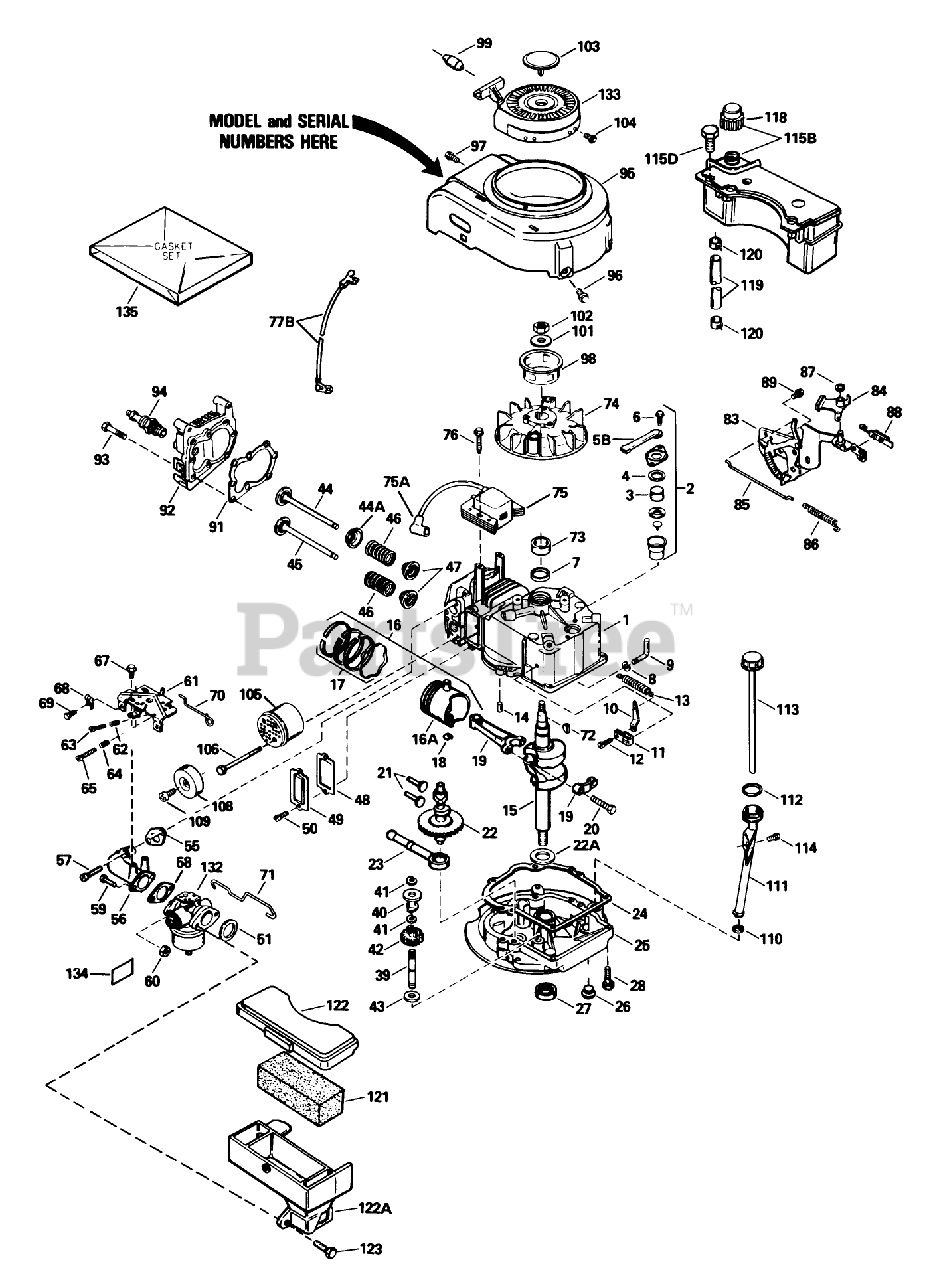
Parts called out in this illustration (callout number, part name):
1	Cylinder Assy. (Incl. #24)
2	Breather Assy. (Incl. Ref. #46 thru 51)
3	Element-Breather
4	Gasket-Breather
5B	Tube, Breaker
6	Screw (10-24 x 9/16)
7	Seal-Oil
8	Washer-Flat
9	Rod, Governor (Incl. No. 36)
10	Governor Lever
11	Clamp-Lever, Governor
12	Screw
13	Spring Governor
14	Pin-Dowel
15	Crankshaft
16	Piston-Pin Ring Assy. (Std.)(Incl. Ref. #16A, 17 18)
16	Piston-Pin Ring Assembly (.010 oversize)(Incl. Ref. #16A, 17 18)
16	Piston, Pin Ring Assy. (.020 Oversize)(Incl. Ref. #13A, 14, 15)
16A	Piston Pin Assy. (Std.)(Incl. Ref. #14)
16A	Piston Pin Assembly (.010 oversize)(Incl. Ref. #18)
16A	Piston Pin Assy. (.020 Oversize) (Incl. Ref. #14)
17	Ring Set-Piston (Std.)
17	Ring Set, Piston(.0100versize)
17	Ring Set (.020" OS)
18	Ring-Retaining, Piston Pin
19	Rod Assy., Connecting (Incl. Ref. #17)
20	Bolt-Rod, Connecting
21	Lifter-Valve
22	Camshaft(Mech.Comp. Release)
22A	Washer-Thrust
23	Oil Pump ASM
24	Gasket
25	Flange-Mounting (Incl. Ref. #26, 27 39)
26	Plug Oil Drain
27	Seal-Oil
28	Screw (1/4-20 x 1-1/4)
39	Shaft-Governor
40	Spool-Governor
41	Ring-Retaining
42	Governor Gear ASM
43	Washer
44	Valve, Intake (Std.) (Incl. Ref. #40)
44	Valve, Intake (1/32" oversize)(Incl. No. 40)
44A	Seal Assy., Intake
45	Valve, Exhaust (Std.)(Incl. No. 40)
45	Valve, Intake (1/32" oversize)(Incl. No. 40)
46	Spring-Valve
47	Cap-Valve, Spring
48	Gasket-Cover, Valve
49	Cover-Valve
50	Screw
51	Gasket-Cleaner, Air
55	Gasket-Intake Pipe
56	Pipe-Intake (Incl. Ref. #59)
57	Screw (1/4-20 x 1)
58	Gasket
60	Nut and Lock Washer (1/4-28)
61	Control Assy.-Remote Speed (Incl. Ref. #69 thru 72 76)
62	61709/GIL1515A/95-5
63	Screw
64	Spring-Compression
65	Screw
67	Screw (10-24 x 9/16)
68	Conduit
69	Screw (10-32 x 3/8)
70	2035A67 ADD.ASSEMBL
71	Link-Throttle
72	Key-Flywheel
73	Spacer
74	Flywheel
75	Solid State
75A	Cover-Spark Plug
76	Screw
77B	Ground Wire
83	Bracket-S.E. Brake
84	Lever-Brake
85	Link-Control
86	Spring-Extension
87	Ring-Retaining
88	Terminal
89	Screw (1/4-20 x 3/8)
91	Gasket-Cylinder Head
92	Head-Cylinder
93	Screw (5/16-18x1-1/2)
94	Spark Plug-Resistor (R J19 L M)
95	Housing-Blower
96	Screw (1/4-20 x 1/2)
97	Screw (10-24 x 9/16)
98	Hub-Starter
99	Retainer-Starter Rope
101	Washer-Belleville
102	Nut-Flywheel
103	Plug Starter
104	Screw, Hex Hd.
105	Muffler (Incl. Ref. #122)
106	Screw
108	Cover-Muffler
109	Screw (8-32 x 3/8)
110	Gasket
111	Oil Fill Tube
112	O-Ring
113	Dipstick
114	Screw (10-32 x 1/2)
115B	Tank Assembly-Fuel (Incl. Ref. #102)
115D	Screw (10-32 x 35/64)
118	Cap-Fuel
119	Line-Fuel
120	Clamp-Line, Fuel
121	Filter-Air Cleaner
122	Cover-Air Cleaner
122A	Body Air cleaner
123	Screw
132	Carburetor (Incl. Ref. #83)
133	Starter-Rewind
134	Decal-Primer
135	Gasket Set (Incl. Items Marked *)
